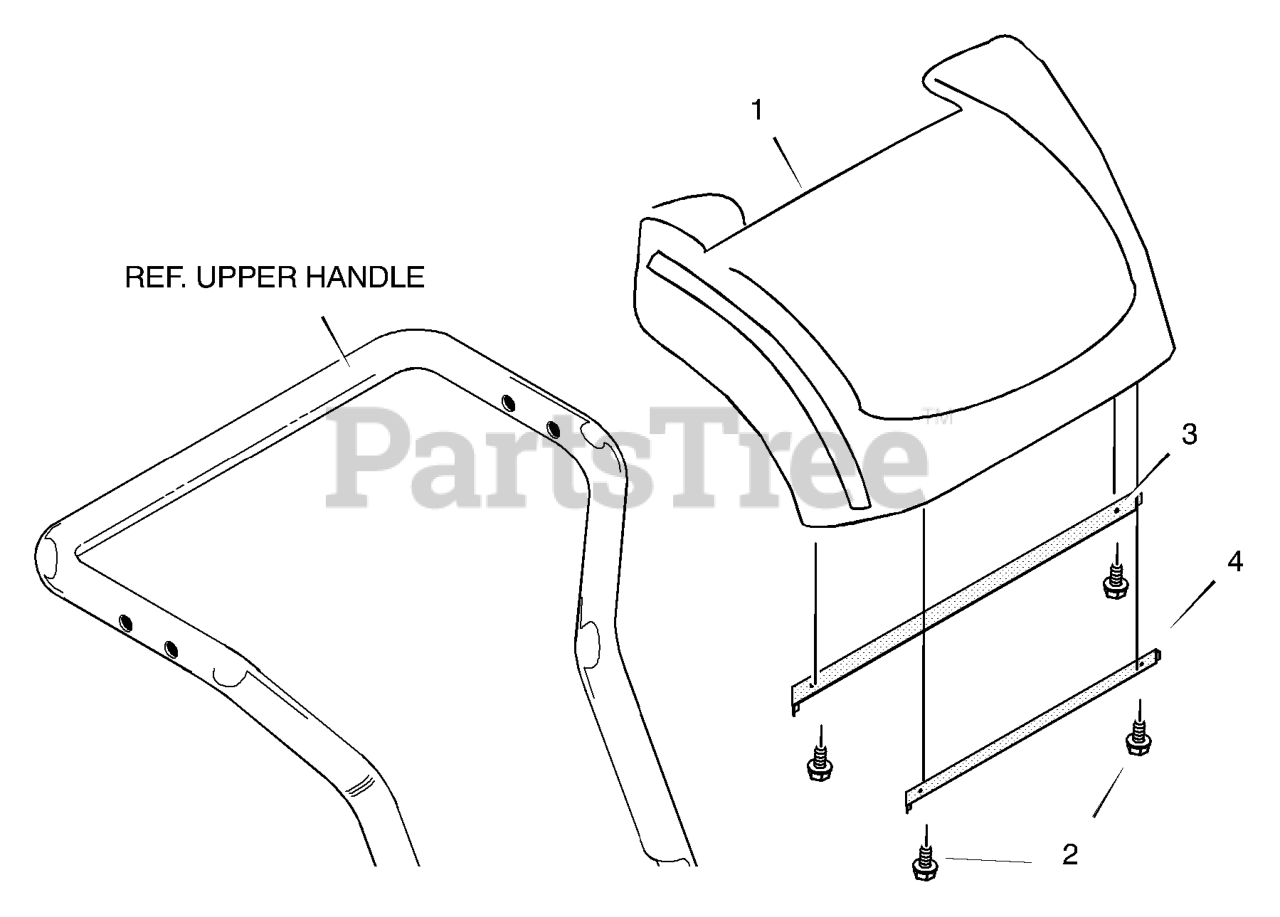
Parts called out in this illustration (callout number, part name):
1	PANEL, CONSOLE
2	SCREW, 10 x 0.62
3	BRACKET, HANDLE COVER -TOP
4	BRACKET, HANDLE COVER -BOTTOM
